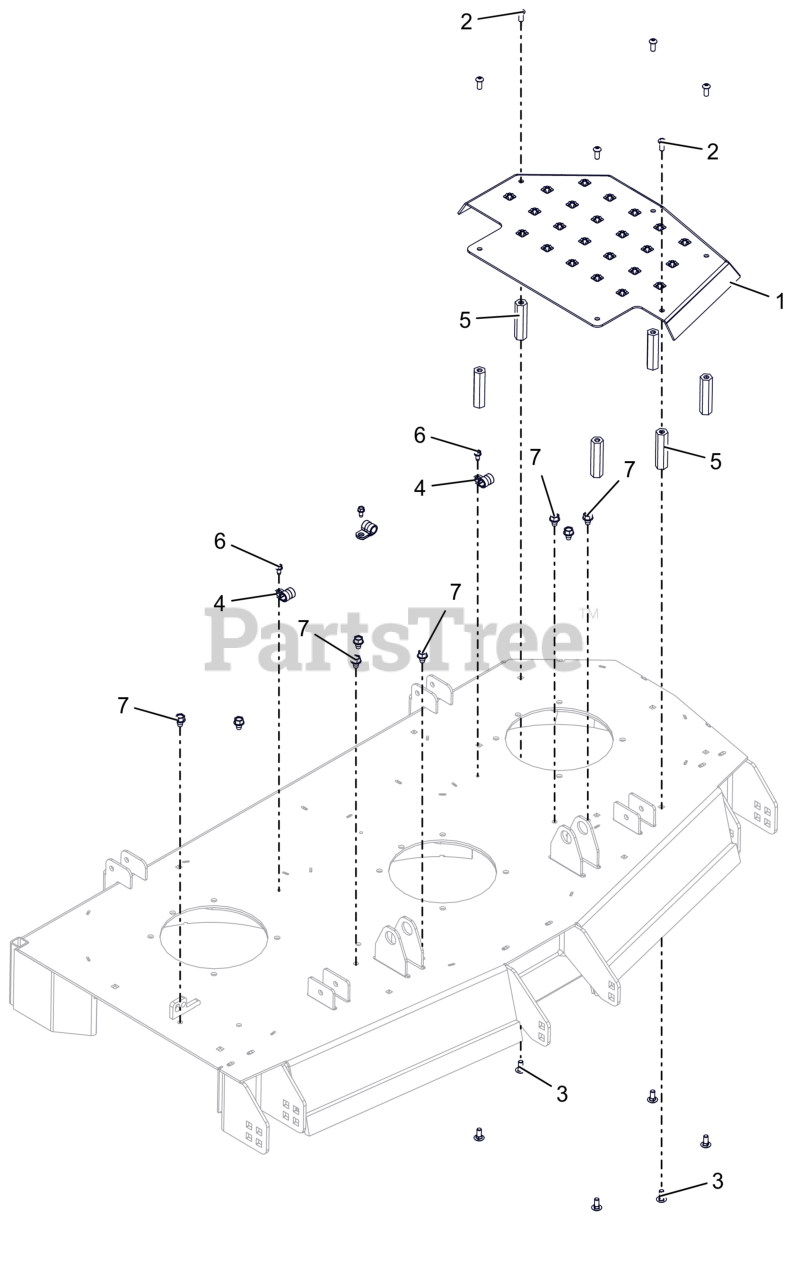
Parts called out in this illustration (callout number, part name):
1	PLATFORM, WLDMT 52 SD DECK STEP (ORANGE)
2	SCR-SKH .31-18X.75 BTNHD YWZC
3	BLT, RHSN .31-18X.75 G5 ZCC LT
4	CLAMP, CUSHIONED STEEL
5	NUT, COUPLING .31-18 X 3.00
6	SCR-TAP .25-20X.50 HWH ZCC
7	SCR,TAP .375-16X.50 HWH TR ZCC
